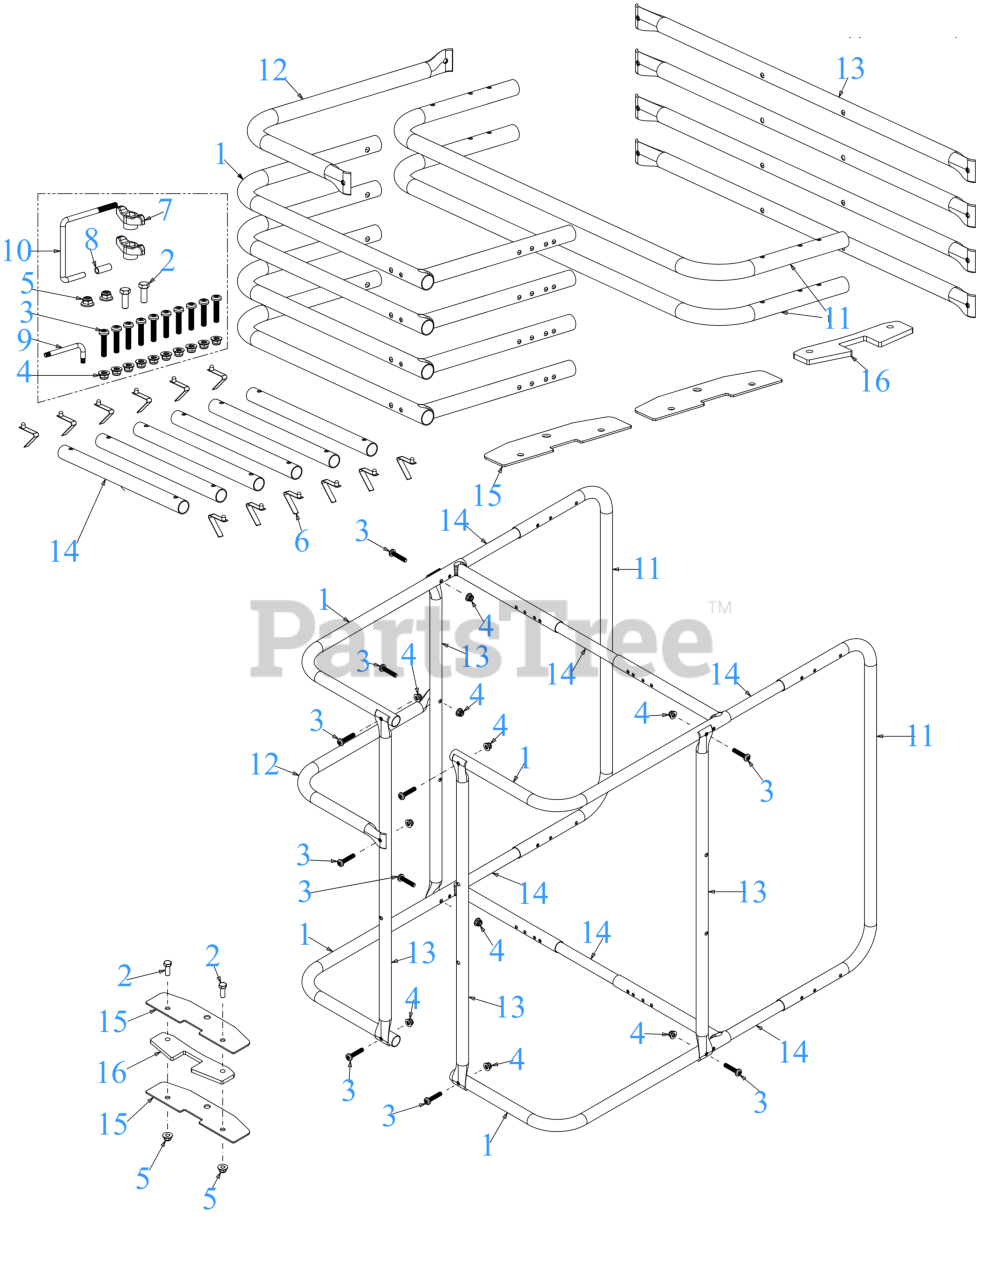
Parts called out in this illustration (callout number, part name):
1	TUBE
2	SCREW 3/8-16 x 1 GR5
4	FLANGE LOCK NUT 5/16-18
6	SPRING BUTTON CLIP
7	WING KNOB 5/16-18
9	TORX TOOL
10	HOOK
11	TUBE
12	TUBE
13	TUBE
14	TUBE
15	STOP PLATE (TOP BOTTOM)
16	STOP PLATE (CENTER)
